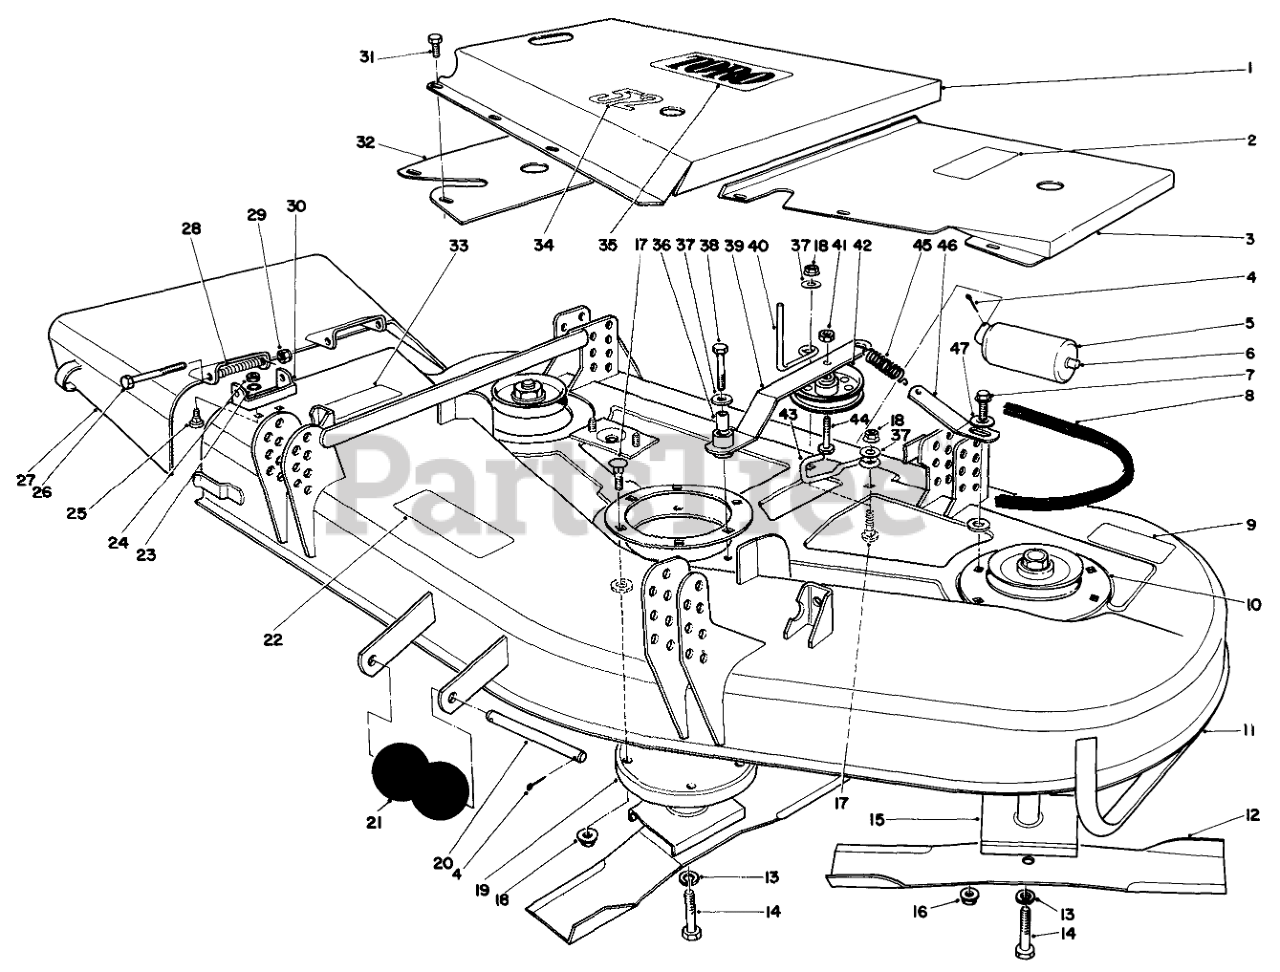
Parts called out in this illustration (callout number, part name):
1	CENTER COVER WA 52 R
2	DECAL
3	Cover
4	PIN-COTTER
5	ROLLER-DECK
6	SHAFT-ROLLER, REAR
7	SCREW-HHF
8	V-BELT
9	DECAL-CAUTION, BLADE
10	SUPPORT-DECK, RING
11	Deck Assembly
12	Blade
13	WASHER-LOCK
14	SCREW-BLADE
15	SPINDLE ASM
16	NUT-LOCK, FLANGE
17	SCREW-CARR
18	NUT-HF
19	HOUSING - SPINDLE ASM
20	SHAFT-ROLLER
21	ROLLER
22	Decal-Caution
23	WASHER-LOCK
24	NUT-HEX
25	SCREW-CARR
26	SCREW-HH
27	Deflector
28	SPRING
29	NUT-HEX
30	Bracket-Pivot
31	SCREW-HHFTF
32	Cover
33	DECAL-CAUTION, DEFLECTOR
34	DECAL
35	Decal-Toro
36	SLEEVE
37	WASHER-FLAT
38	SCREW-HH
39	Arm-Idler
40	ROD-BELT
41	NUT-HEX
42	Pulley
43	GUIDE-BELT
44	Bolt-Special
45	SPRING-EXTENSION
46	PLATE-SPRING
47	WASHER-FLAT
